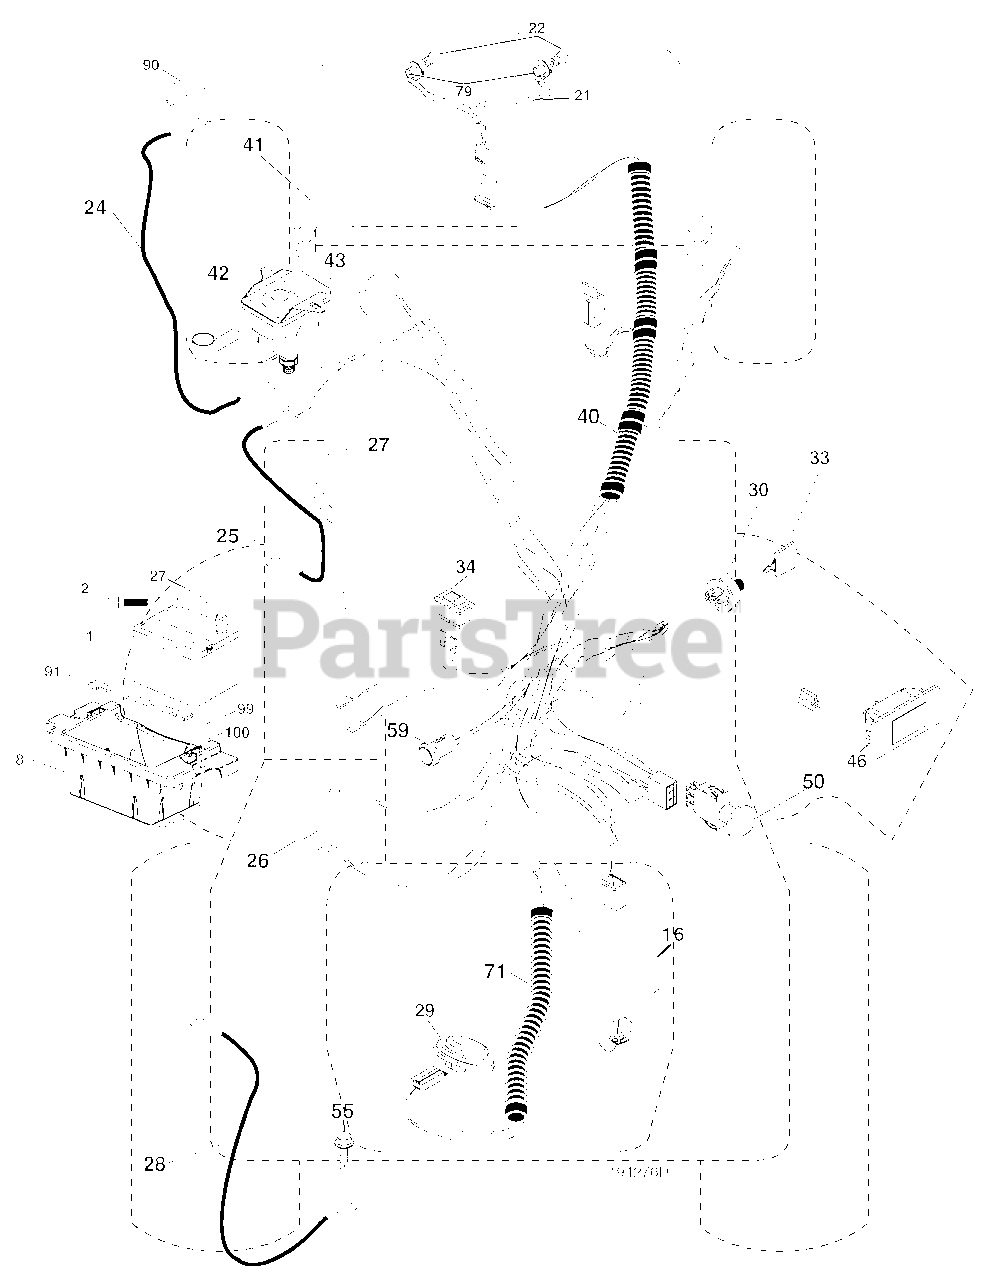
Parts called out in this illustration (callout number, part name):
1	Battery
2	Bolt Hex Head 1/4-20 x 3/4
8	Box Battery
16	Switch Interlock Push-In
21	Harness Socket Light W/4152J
22	Bulb Light
24	Cable Battery
25	Cable Start Red
26	Fuse
27	Nut Keps Hex 1/4-20 unc
28	Cable, Ground
29	Switch, Seat
30	Switch, Ignition
33	Key, Ignition
34	Switch Light / Reset
40	Harness Ignition
41	Screw Thd Cut 1/4-20 x 1/2
42	Cover, Terminal
43	Solenoid
46	Gauge Hourmeter
50	Switch, PTO
55	Screw Thdrol 5/16-18 x 3/4 TYTT
59	Outlet 12-Volt
71	Harness Ign. Dash
79	Bulbholder Asm. Incan Descent
90	Cover Terminal Battery
91	Strap Battery Mount Front
99	Screw Hexwsh Thdrol 1/4-20 x 3/4
100	Washer 9/32 x 7/8 x 16 Ga.
100	Harness Pigtail Trans.
